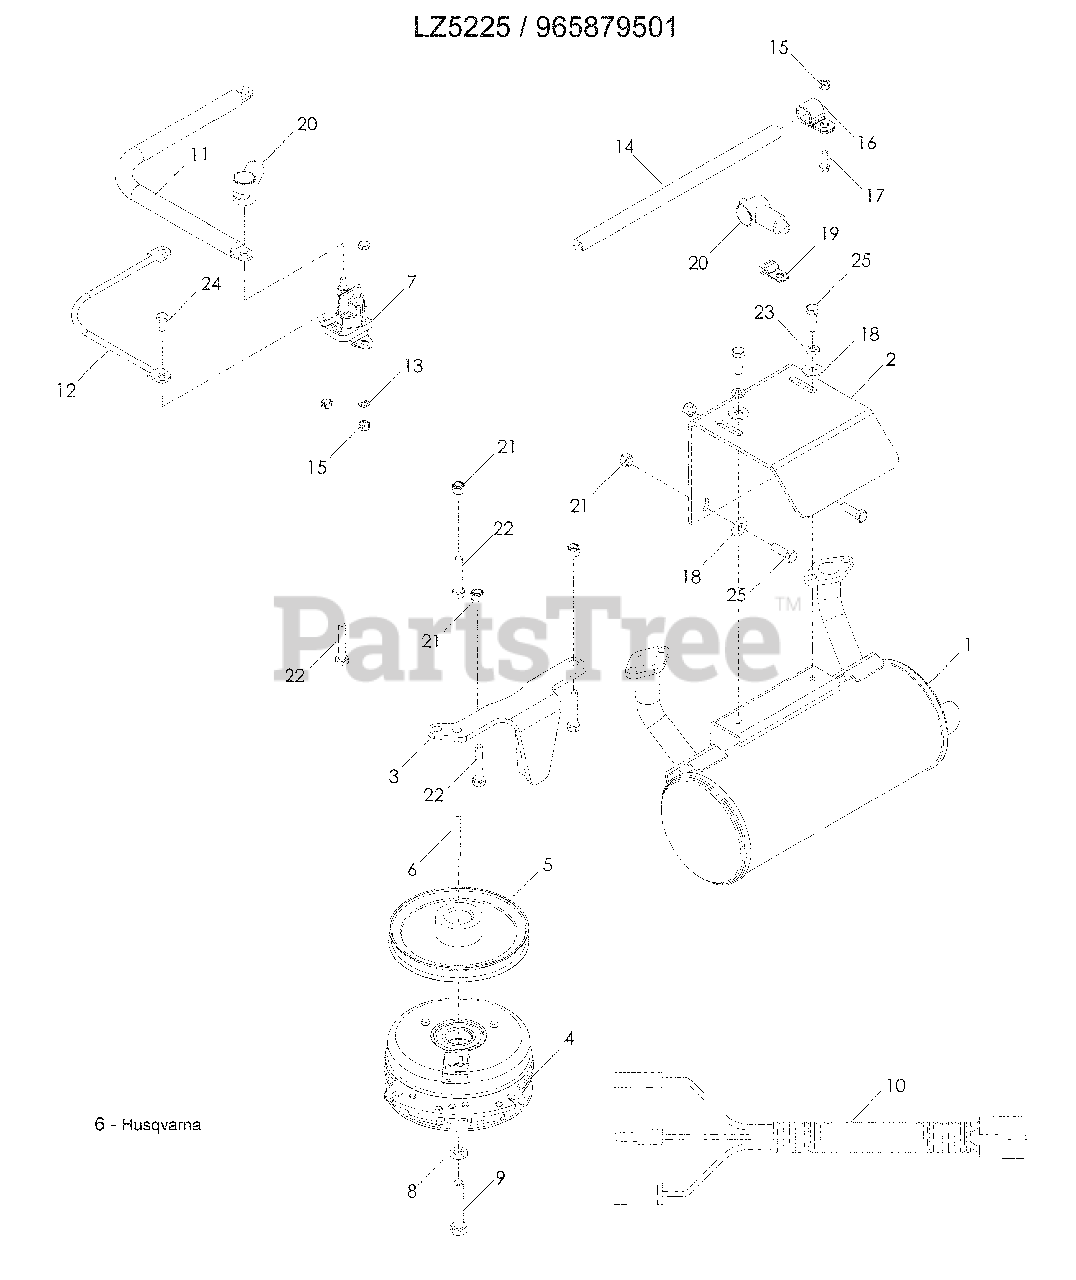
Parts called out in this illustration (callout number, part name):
2	BRACKET, MUFFLER
3	TIE DOWN, CLUTCH
4	CLUTCH, 200 FT/LBS
8	WASHER 7/16 SLW
9	HCS 7/16 x 2½
11	CABLE, POSITIVE
12	GROUND WIRE
13	WASHER ¼ ITLW
14	HOSE, OIL DRAIN
15	NUT ¼-20 CNTRLK
17	HCS ¼-20 x ¾
18	WASHER 5/16 STD FLT
19	CLAMP, DOUBLE TUBE
21	NUT 5/16-18 HEX NYLOC
22	HCS 5/16-18 x 1¾
23	WASHER 5/16 SLW
24	HCS ¼-20 x 5/8
25	HCS 5/16-18 x 1
